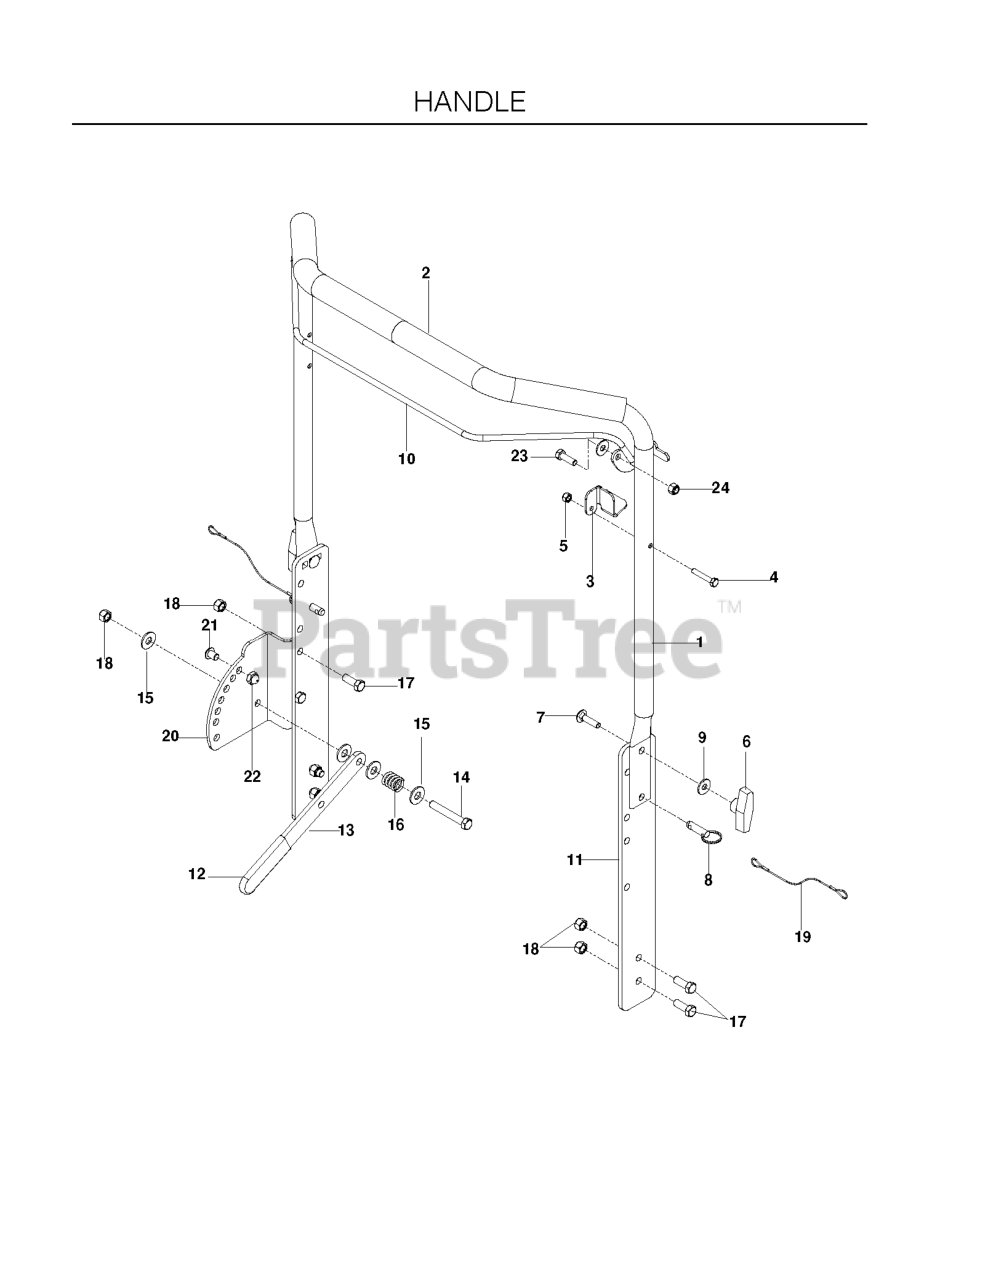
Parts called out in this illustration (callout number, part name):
1	HANDLE GRAY
3	CABLE TAB POWER RAKE
4	SCW 1/4-20 X 1-1/2 HEX
5	NUT.1/4-20.HEX.NYLOC.ZD
7	BOLT, CARRIAGE 5/16X1-1/4
8	DETENT PIN RAKE/DT
9	WASHER 5/16 FLAT
10	BAIL - ORANGE
11	HANDLE SIDE GRAY
13	LEVER, PLATED
14	HCS 3/8C X 2 1/2
15	WASHER 3/8 FLAT
16	COMPRESSION SPRING
17	HCS 3/8-16X1.GRD.5.ZD
18	NUT 3/8-16 NYLOC
20	HEIGHT ADJUSTMENT PLATE
21	BLT 3/8-16 X 1/2 BTN HD BLK SP
22	NUT 3/8-16 ACORN HEX
23	HCS 5/16C X 1
24	NUT 5/16 NYLOC
